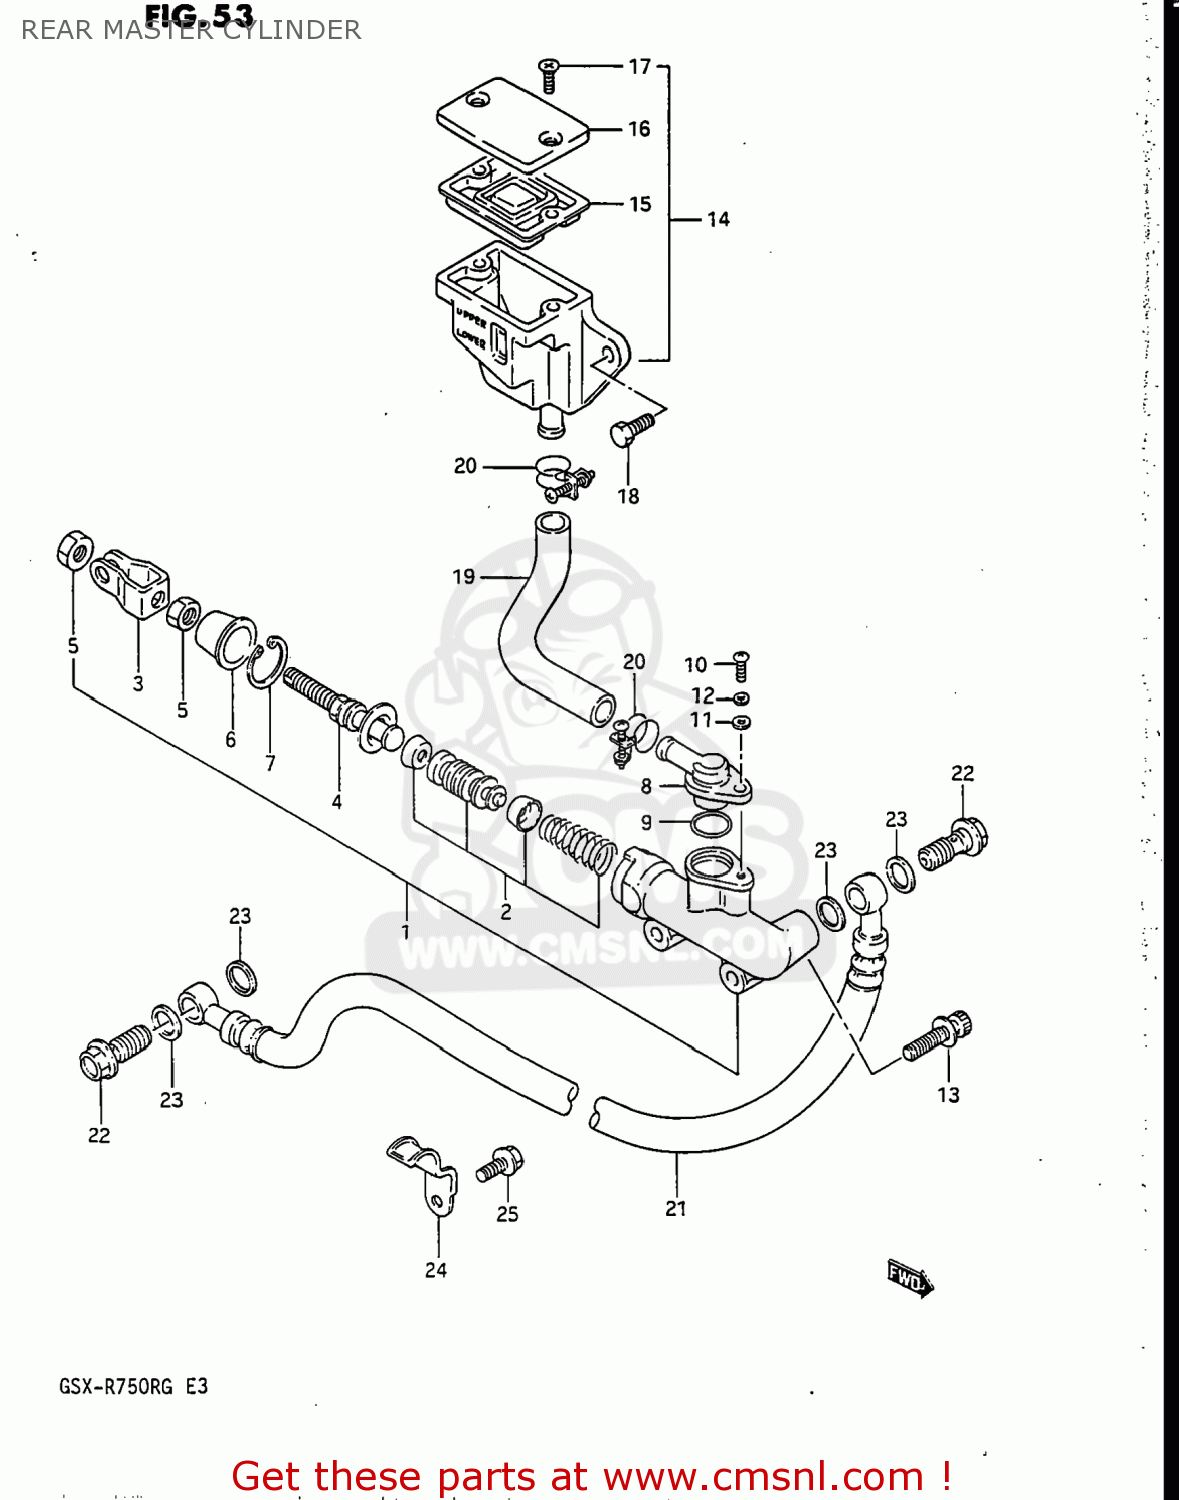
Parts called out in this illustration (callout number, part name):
1	CYLINDER ASSY,RR MASTER
2	PISTON/CUP SET
3	YOKE
4	ROD,PUSH
5	NUT
6	BOOT
7	CIRCLIP
8	CONNECTOR
9	O RING
10	SCREW
11	WASHER
12	LOCK WASHER
13	BOLT
14	TANK ASSEMBLY,RESERVOIR
15	DIAPHRAGM
16	CAP
17	SCREW
18	BOLT
19	HOSE,RESERVOIR TANK
20	CLAMP
21	HOSE,REAR BRAKE
22	BOLT UNION
23	WASHER(10X15X1.5)
24	CLAMP,REAR BRAKE HOSE NO
25	BOLT
